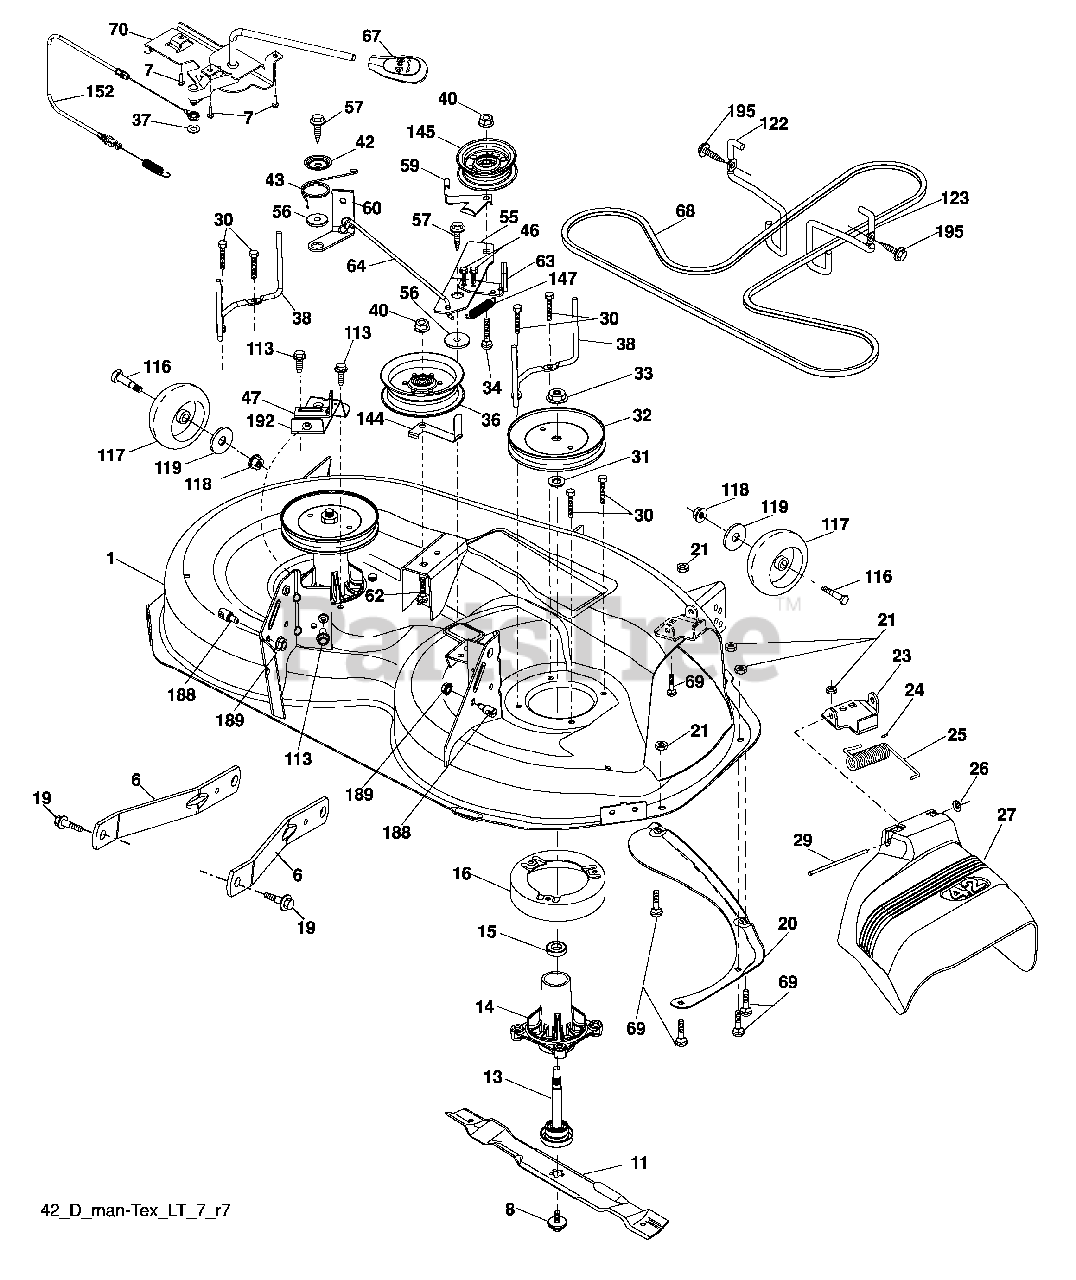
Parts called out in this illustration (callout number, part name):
1	Mower Housing
6	Arm Suspension
7	Screw 10 x 3/4 Single Lead Hex
8	Bolt/Washer Asm 7/16-20 unf
11	Blade, 42" Hi-Lift
13	Shaft Assembly, Mandrel
14	Housing, Mandrel
15	Bearing, Ball, Mandrel
16	Stripper, Mower Deck
19	Bolt, Shoulder
20	Baffle, Vortex
21	Nut, Crownlock 5/16-18 unc
23	Bracket, Deflector
24	Cap, Sleeve
25	Spring, Torsion, Deflector
27	Shield, Deflector
29	Rod, Hinge
30	Screw Thdrol Rolling Wsh Hd
31	Washer, Spacer
32	Pulley, Mandrel
33	Nut, Toplock, Flanged
34	Bolt Carr Sh. 3/8-16 x 1-1/2 Gr. 5
36	Pulley, Idler, Flat
37	Washer
38	Keeper Belt LH Mandrel
40	Nut, Lock Flg. 3/8-16 unc
42	Spring Torsion Brake
43	Spring Torsion Retainer
46	Screw Thd Roll 1/4-20 x 5/8
47	Bracket Clutch Cable
55	Arm, Idler
56	Spacer, Retainer
57	Screw 3/8-16 x 1
59	Guard, Tuv Idler
60	Arm Brake Mower
62	Bolt Rd Hd Sq Nk 3/8-16 unc x 2
63	Arm Brake Mower
64	Link Brake
67	Handle Clutch Cable
68	V-Belt
69	Bolt
70	Clutch Asm Manual
113	Screw 5/16-18
116	Bolt, Shoulder
117	Wheel, Gauge
118	Nut, Crownlock 3/8-1
119	Washer 13/32 x 7/8 x 14 Ga.
122	Keeper Belt Engine LH
123	Keeper Belt Engine RH
144	Keeper Belt
145	Pulley Idler
147	Spring Return
152	Manual Clutch Cable
188	Stud Fastener
189	Nut Lock Hex Flange
192	Bracket Brake Stand LH
195	Screw 3/8-16 x 3/4
